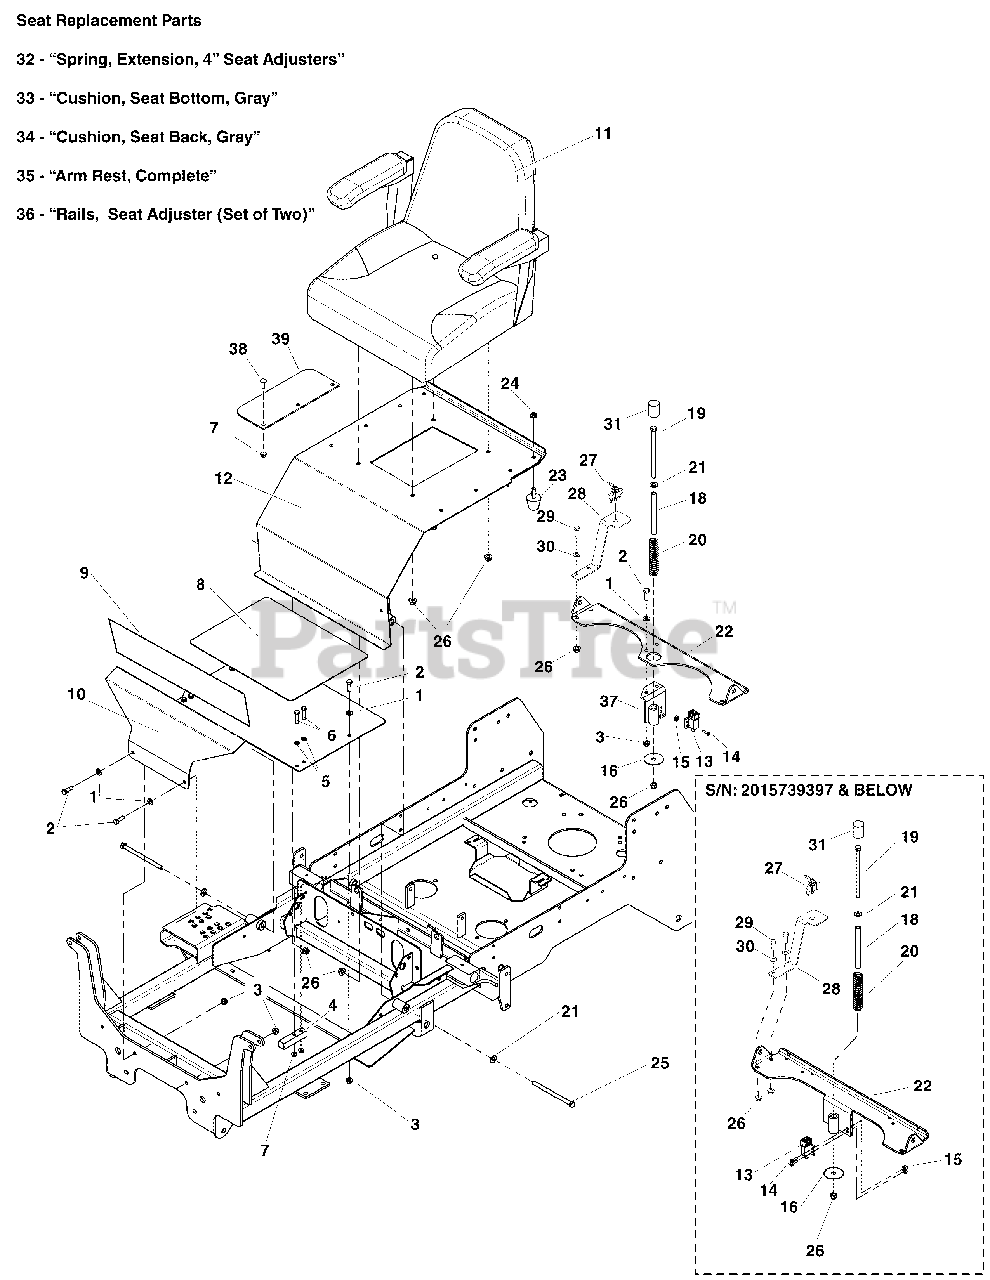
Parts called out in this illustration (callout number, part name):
1	WASHER, 5/16" SAE
2	BOLT, 5/16-18 X 1" GD5
3	NUT, 5/16-18 HEX NYLOCK FLANGE
4	BLOCK, DECK LIFT SUPPORT
5	WASHER, 1/4 SAE (5025154)
6	BOLT, 1/4-20 X 1-1/4" GD5
7	NUT, 1/4-20 HEX NYLOCK FLANGE (5025391)
8	SAFETY WALK, 11.50 X 15.00
9	SAFETY WALK, 8.00 X 15.00
10	PLATE, FLOOR, IS2000
11	SEAT, 2012
11	SEAT, LOW, COMPANION
11	SEAT, GRAY, COMPLETE
12	WELD, SEAT PLATE
13	SWITCH PLUNGER N.C. / N.C.
14	SCREW- #10-24 X 1/2 ROUND PHILLIPS
15	NUT, HEX, #10-24
16	WASHER 3/8" X 2
17	NUT, 3/8-16 HEX NYLON LOCK
18	SPACER, .38 X .50 X 5.06
19	BOLT, 3/8-16 X 6" GD5
20	SPRING, .688 ID X .130 WIRE DIA 4.25
21	WASHER 3/8" SAE
22	PLATE, SEAT SUPPORT
22	WELD, SEAT SUPPORT
23	BUMPER, RUBBER 5/16-18
24	NUT, 5/16-18 HEX SM. SERR. FLG.
25	BOLT, 3/8-16 X 5-1/2" GD5
26	NUT, 3/8-16 HEX NYLOCK FLANGE
27	VALVE, FUEL, STR. OUTLET
28	MOUNT, FUEL SELECTOR SWITCH - BLK
29	BOLT, 3/8-16 X 1-1/4 GD5
30	WASHER, 3/8" SAE
31	CAP, VINYL, .937 ID X 1.00
32	SPRING, EXTENSION, SEAT ADJUSTMENT (YEL OR BLK)
33	CUSHION, SEAT BOTTOM
34	CUSHION, SEAT BACK
35	ARM REST, COMPLETE
36	RAILS, SEAT ADJUSTER
37	BRACKET, SPRING SWITCH
38	BOLT, 1/4-20X.750, SQ
39	PLATE, SEAT, RUBBER FLAP
